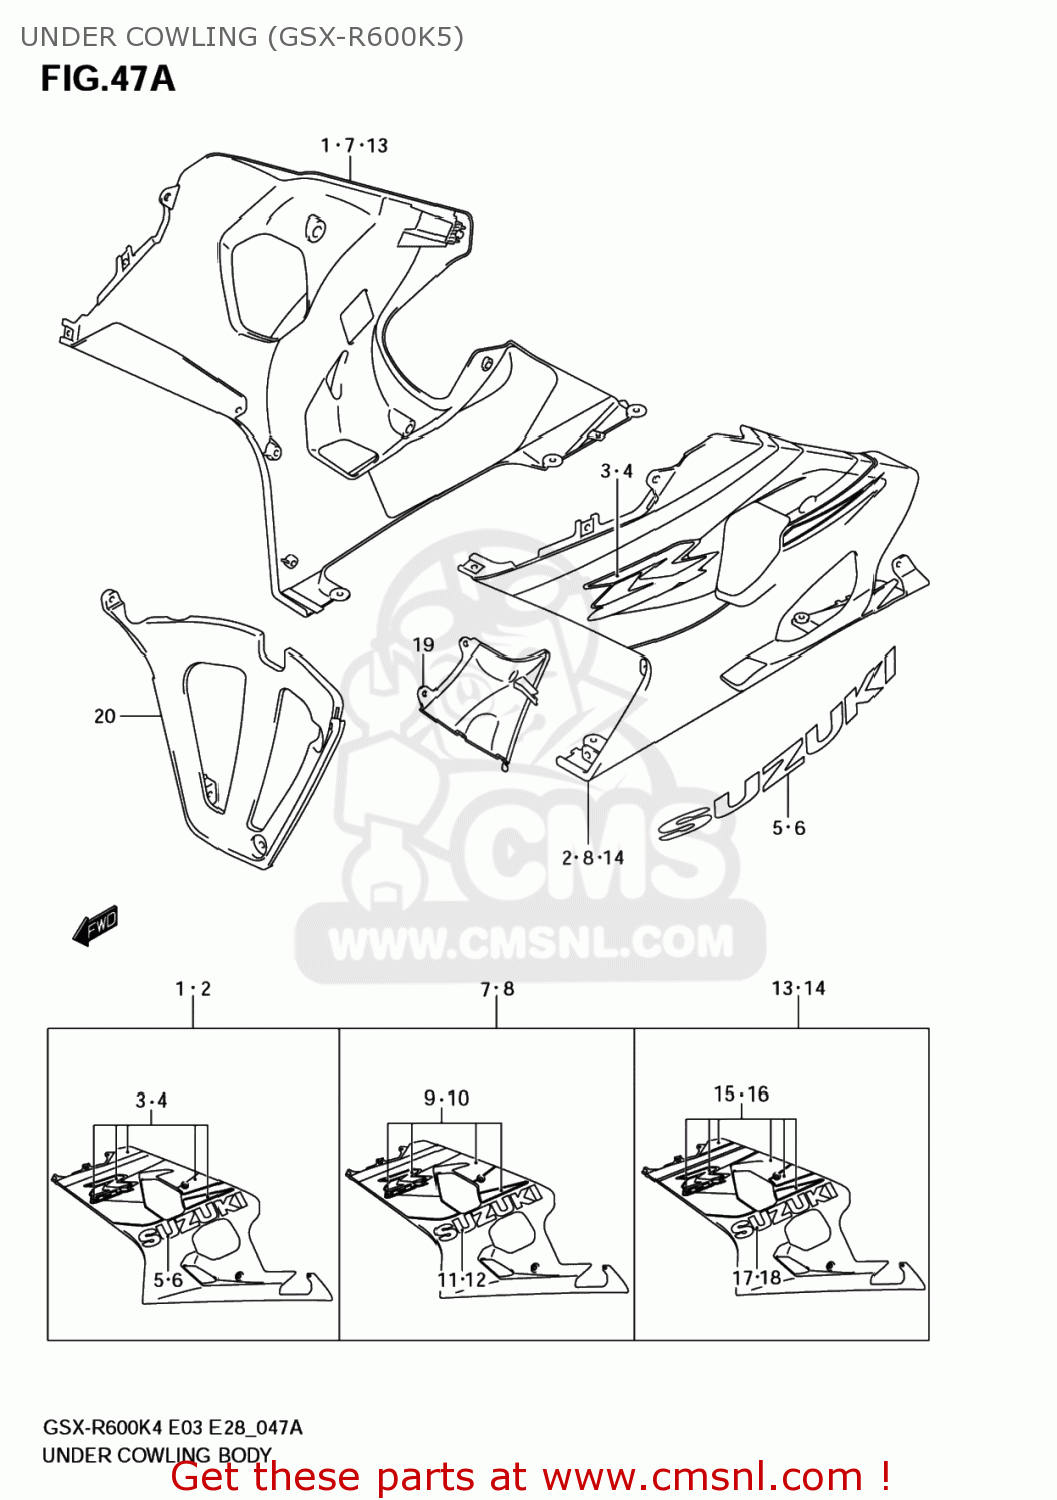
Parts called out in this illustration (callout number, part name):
1	COWLING ASSY,UNDER,R
2	COWLING ASSY,UNDER,L
3	TAPE SET,UNDER,R
4	TAPE SET,UNDER,L
5	EMBLEM,R
6	EMBLEM,L
7	COWLING ASSY,UNDER,R
8	COWLING ASSY,UNDER,L
9	TAPE SET,UNDER,R
10	TAPE SET,UNDER,L
11	EMBLEM,R
12	EMBLEM,L
13	COWLING ASSY,UNDER,R
14	COWLING ASSY,UNDER,L
15	TAPE SET,UNDER,R
16	TAPE SET,UNDER,L
17	EMBLEM,R
18	EMBLEM,L
19	COWLING,UNDER INNER,L
20	COWLING,UNDER CTR
